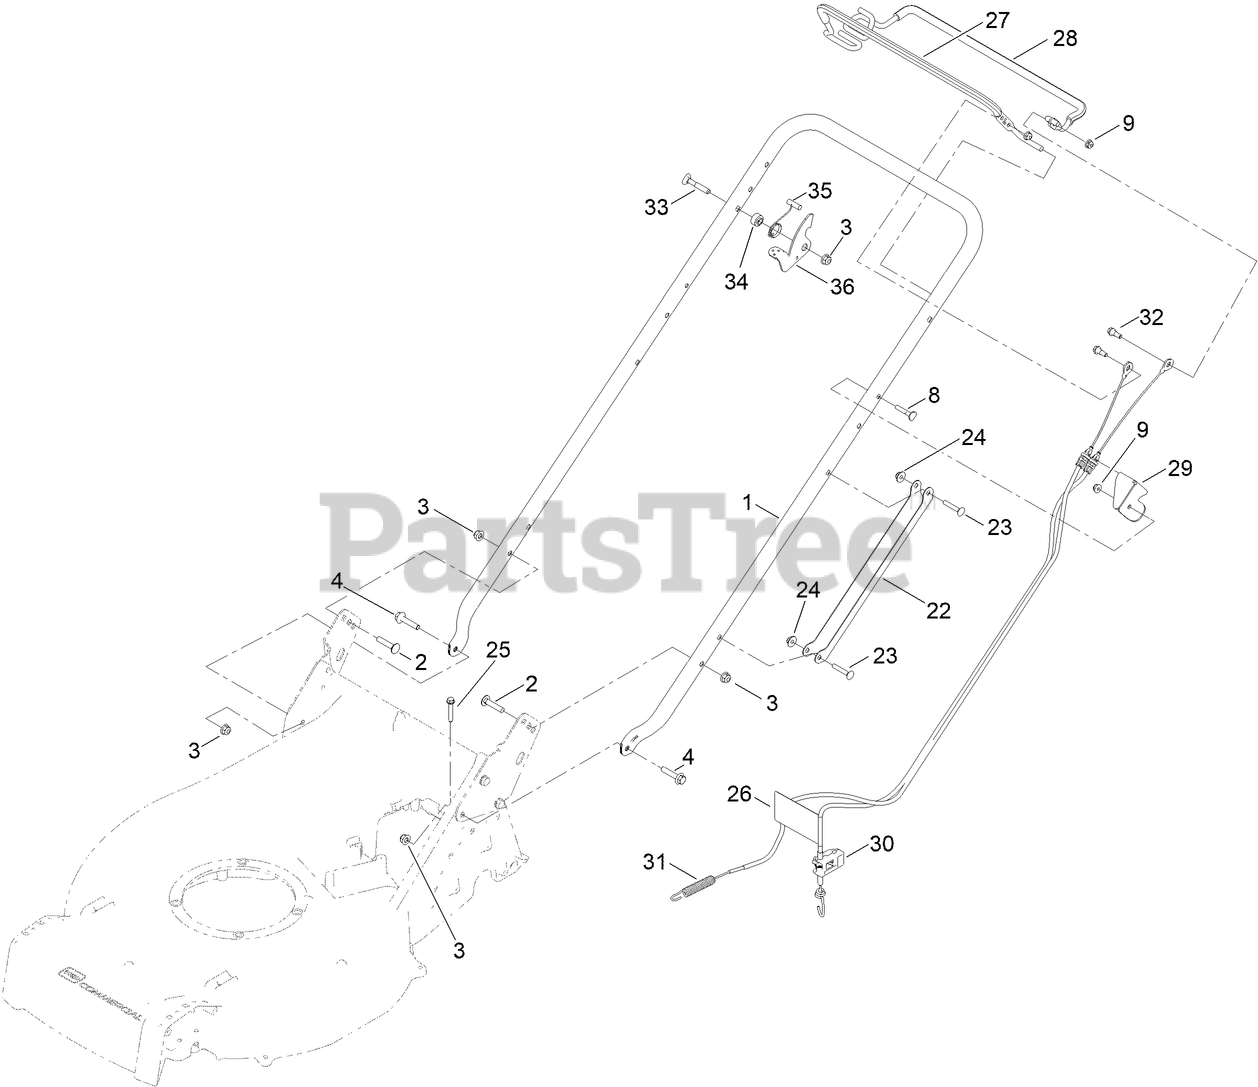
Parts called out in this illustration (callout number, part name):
2	BOLT-CARR
3	NUT-HF, NI
4	SCREW-HHF
8	SCREW-HANDLE
9	NUT-HF
22	GUARD-CABLE, HANDLE
23	SCREW-CARR
24	NUT-HF
25	SCREW-HWH
27	BAIL-BBC, COATED
28	BAIL-TRACTION, COATED
29	BRACKET-CABLE
30	CABLE-TRACTION
31	CABLE-BBC
32	BOLT-SHOULDER
34	BUSHING-STEPPED
35	SPRING-LEVER, BBC
36	LEVER-BBC
